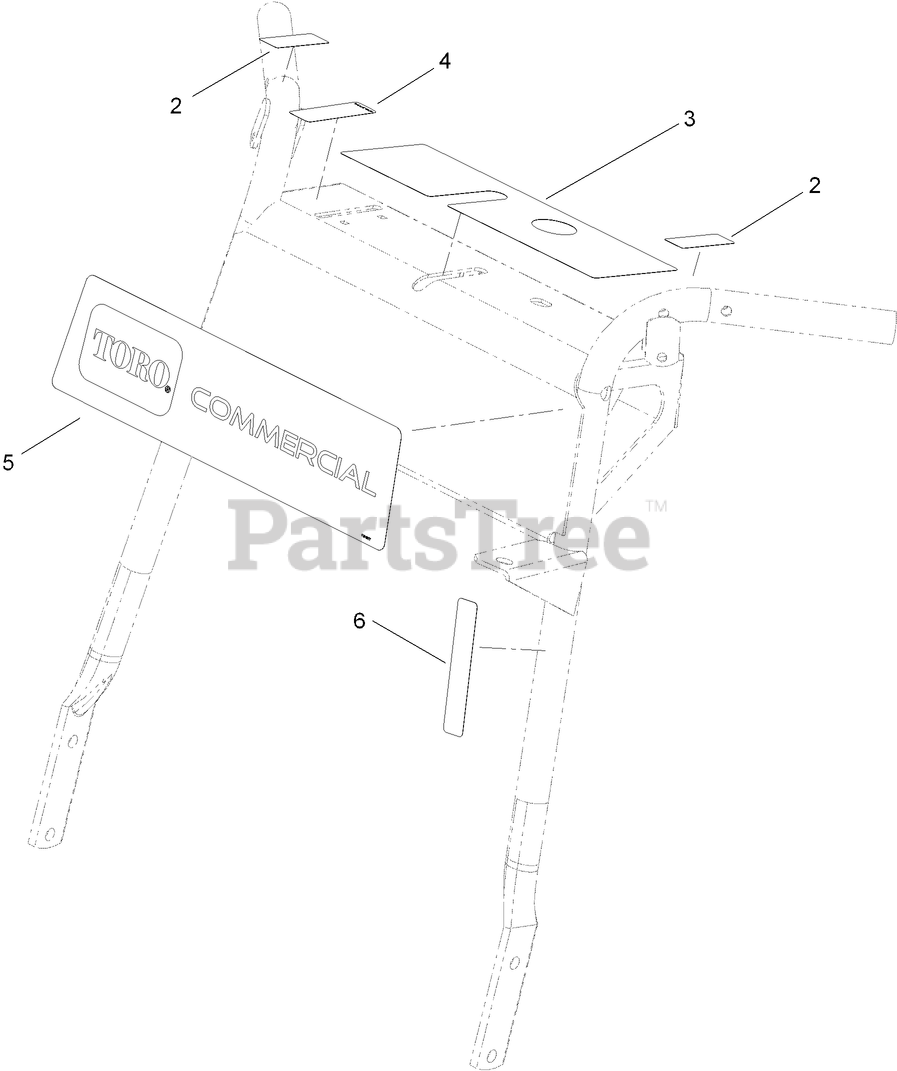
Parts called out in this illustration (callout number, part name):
2	DECAL-LOCK, NEUTRAL
3	DECAL-PANEL, CONTROL
4	DECAL-THROTTLE
6	DECAL-ENGAGE, DECK
